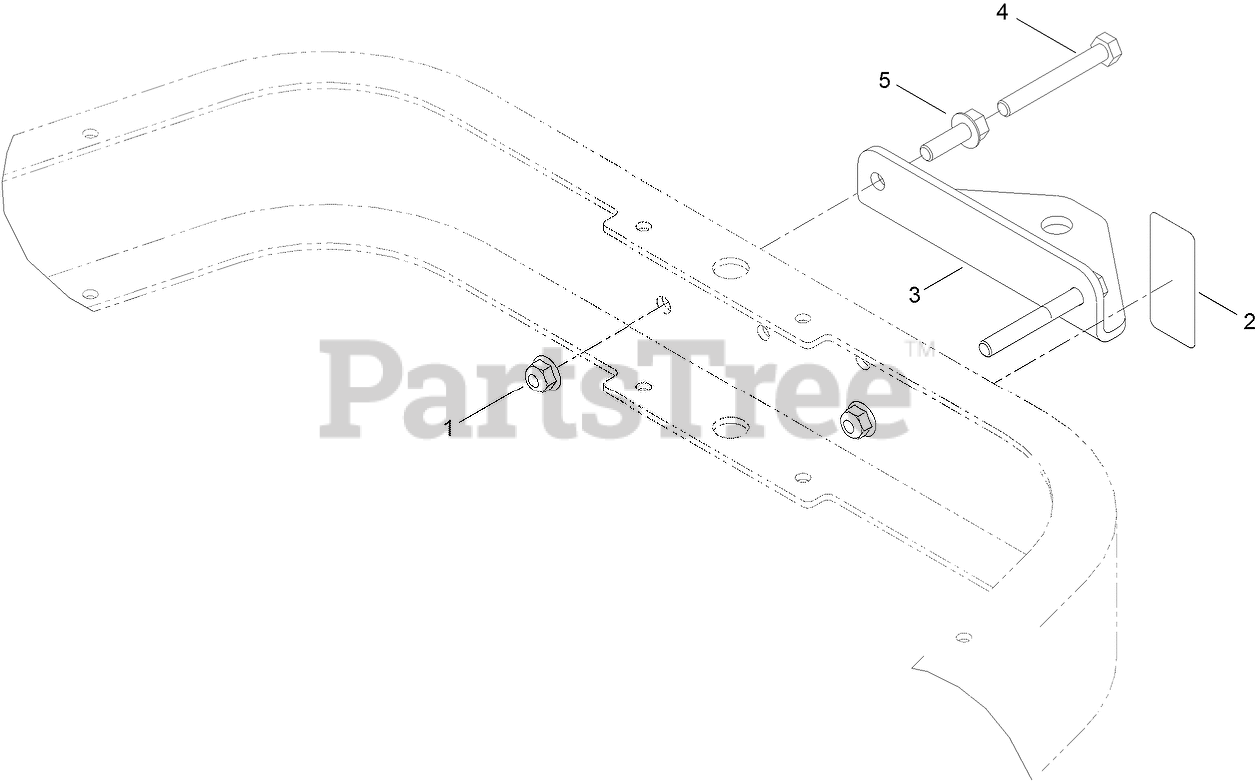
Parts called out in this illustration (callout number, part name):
1	NUT-HF, NI
3	BRACKET-HITCH
4	SCREW-HH (5/16-18 X 2.50, GR5)
5	SCREW-HHF (5/16-18 X 1, GR5)
